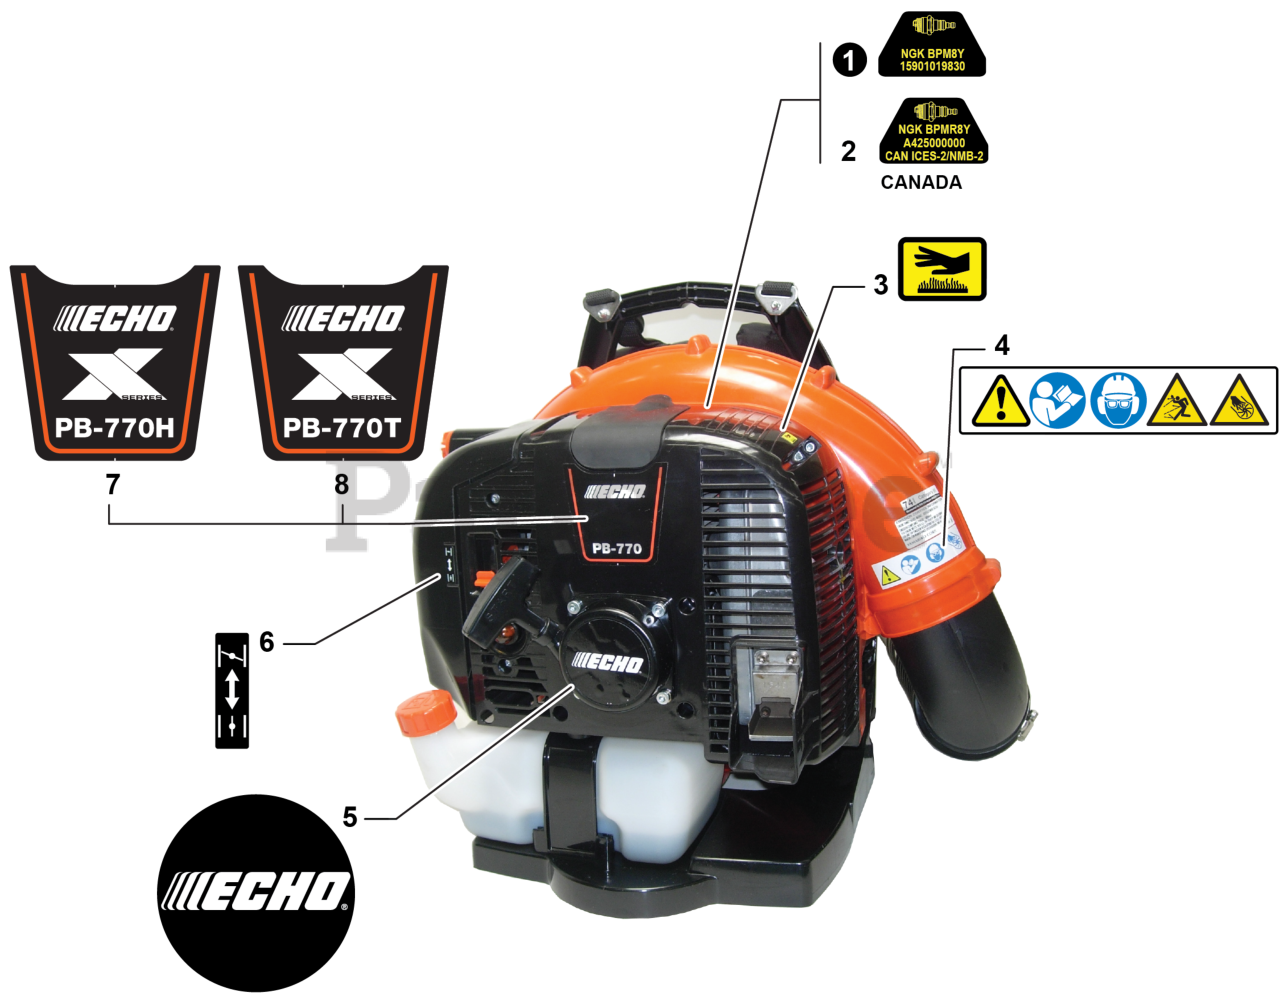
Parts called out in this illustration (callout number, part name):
1	LABEL - SPARK PLUG - BPM8Y
2	LABEL - SPARK PLUG - BPMR8Y
3	LABEL - CAUTION - HOT
4	LABEL - CAUTION - ISO
5	LABEL - STARTER - ECHO
6	LABEL - CHOKE
7	LABEL - PB-770H
8	LABEL - PB-770T
